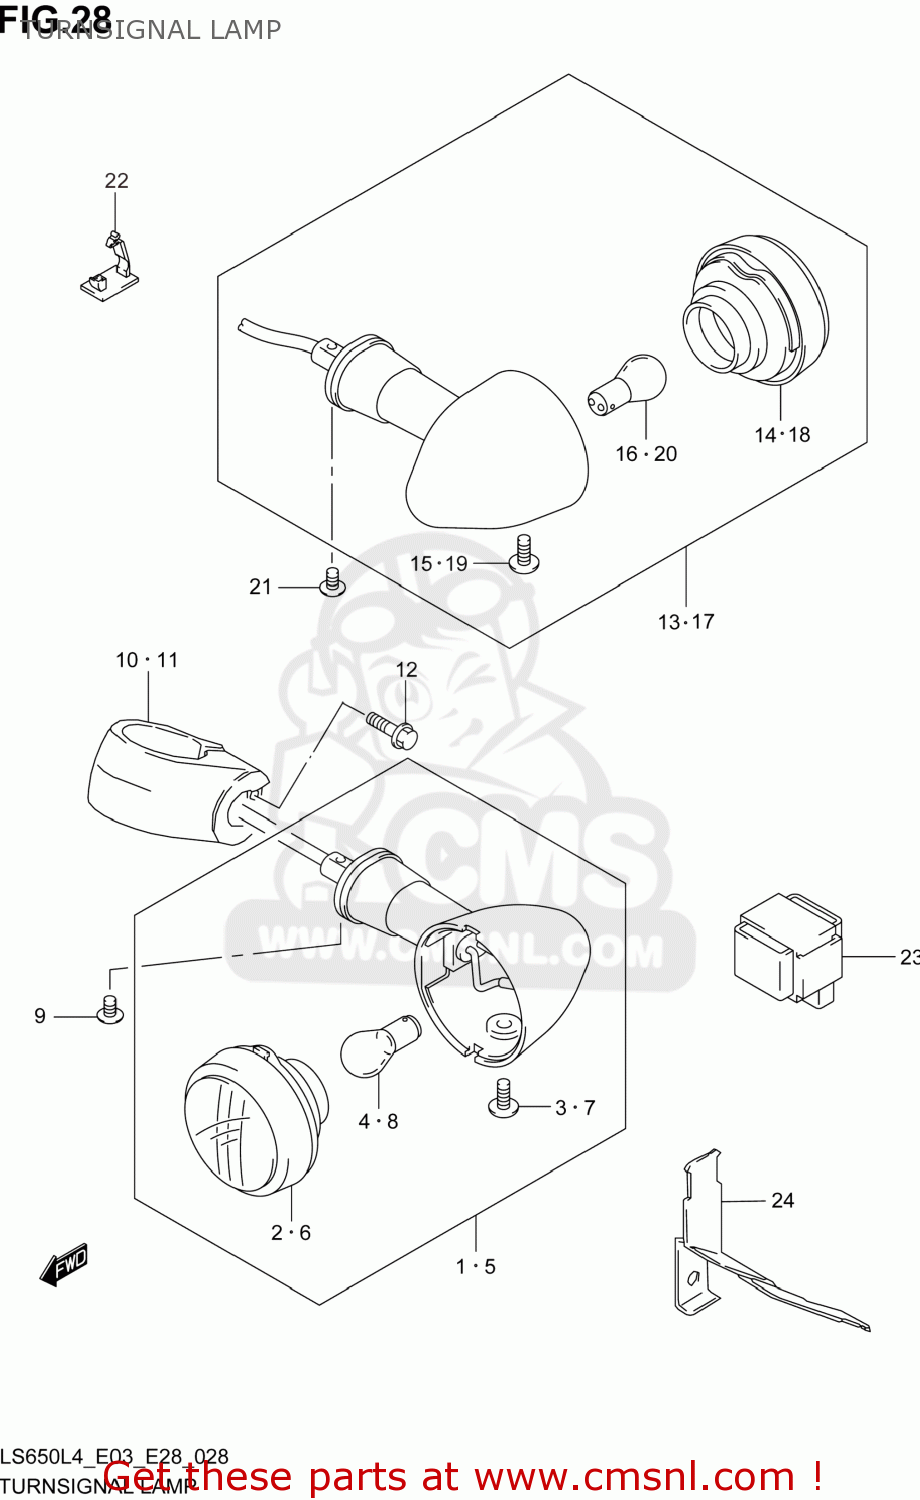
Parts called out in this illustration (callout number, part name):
1	LAMP ASSY,FR TURN SIGNAL,R
2	LENS
3	SCREW(4X10)
4	BULB(12V21/5W)
5	LAMP ASSY,FR TURN SIGNAL,L
6	LENS
7	SCREW(4X10)
8	BULB(12V21/5W)
9	SCREW
10	BRACKET,FR TURNSIGNAL LAMP,R
11	BRACKET,FR TURNSIGNAL LAMP,L
12	BOLT
13	LAMP ASSY,RR TURNSIGNAL,R
14	LENS
15	SCREW(4X10)
16	BULB(12V21W)
17	LAMP ASSY,RR TURNSIGNAL,L
18	LENS
19	SCREW(4X10)
20	BULB(12V21W)
21	SCREW
22	CLAMP
23	RELAY ASSY
24	BRACKET,TURNSIGNAL RELAY
